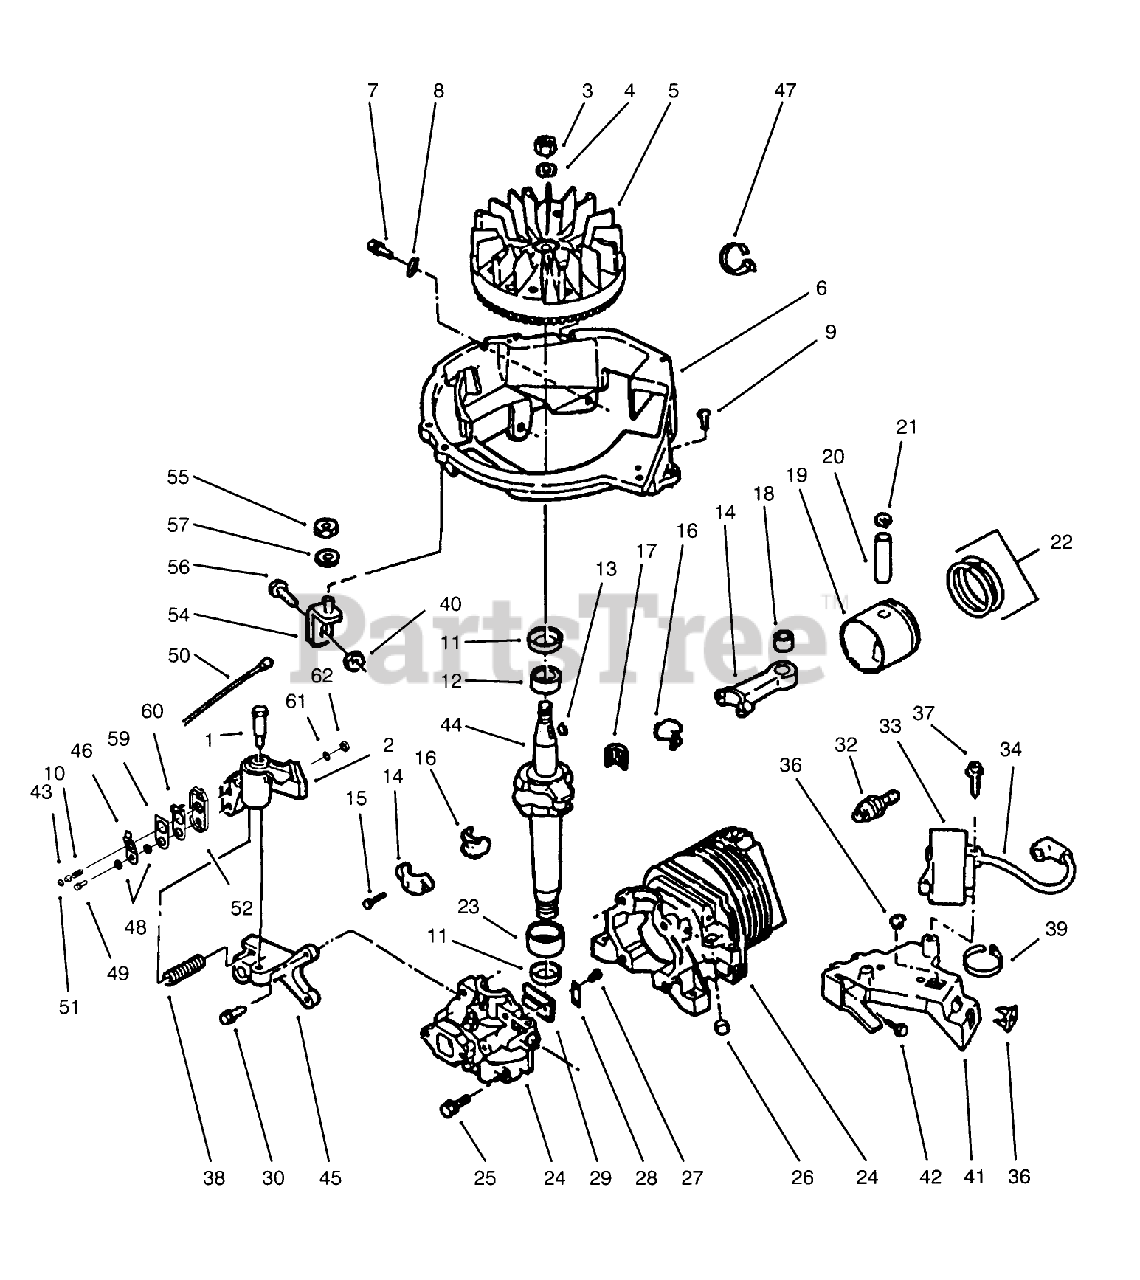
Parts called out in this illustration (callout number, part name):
1	SCREW-SHOULDER
5	FLYWHEEL ASSY F
6	BASE SHROUD F
7	SCREW-SEMS
9	SCREW F
11	SEAL-OIL
12	BEARING V
14	CONNECTING ROD ASM
15	SCREW-HSH
16	LINER ASM
17	BEARING-NEEDLE
18	BEARING XEV
21	RING-RETAINING
23	BEARING V
25	SCREW-H.W.HD. F
26	PLUG-CORE VF
27	SCREW-HH
28	PLATE-BACKUP, REED
32	SPARK PLUG
34	HT LEAD&COVER XEV
36	NUT-CLIP
38	SPRING-BRAKE
39	TIE-CABLE
40	NUT-LOCK F
41	C.D. BRKT F
42	SCREW F
43	ACTUATOR-LEVER, BRAKE
45	BRACKET-BRAKE F
46	SPRING-CONTACT
49	SCREW-HH
50	WIRE LEAD AY F
51	RETAINER S
52	CASE - SWITCH EF
54	BRACE AY F
55	LOCKNUT E
60	PLATE-CONTACT
61	WASHER-LOCK/EXT
